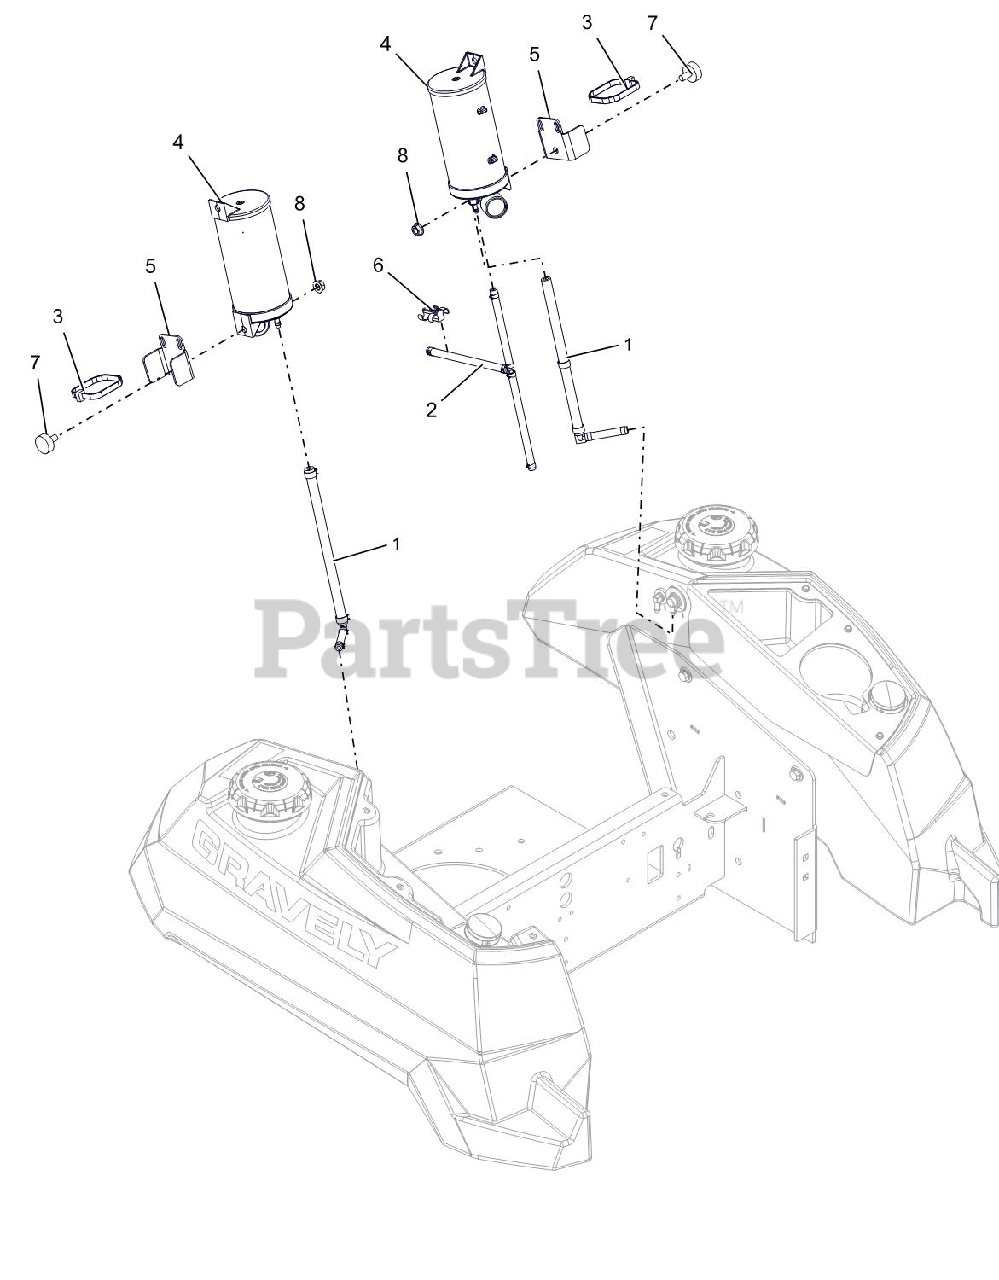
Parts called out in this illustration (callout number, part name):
1	ASM, CANISTER VENT LINE
2	ASM, VAPOR LINE (CARB)
3	TIE WRAP, 15.25" X 120 LBS
4	CANISTER, 400 CC CARB
5	BRKT, CARB CANISTER MOUNTING
6	CLIP, T, .38-.50
7	BUMPER, RUBBER
8	@NUT-SPNLK-FLG .312-18 YWZC
